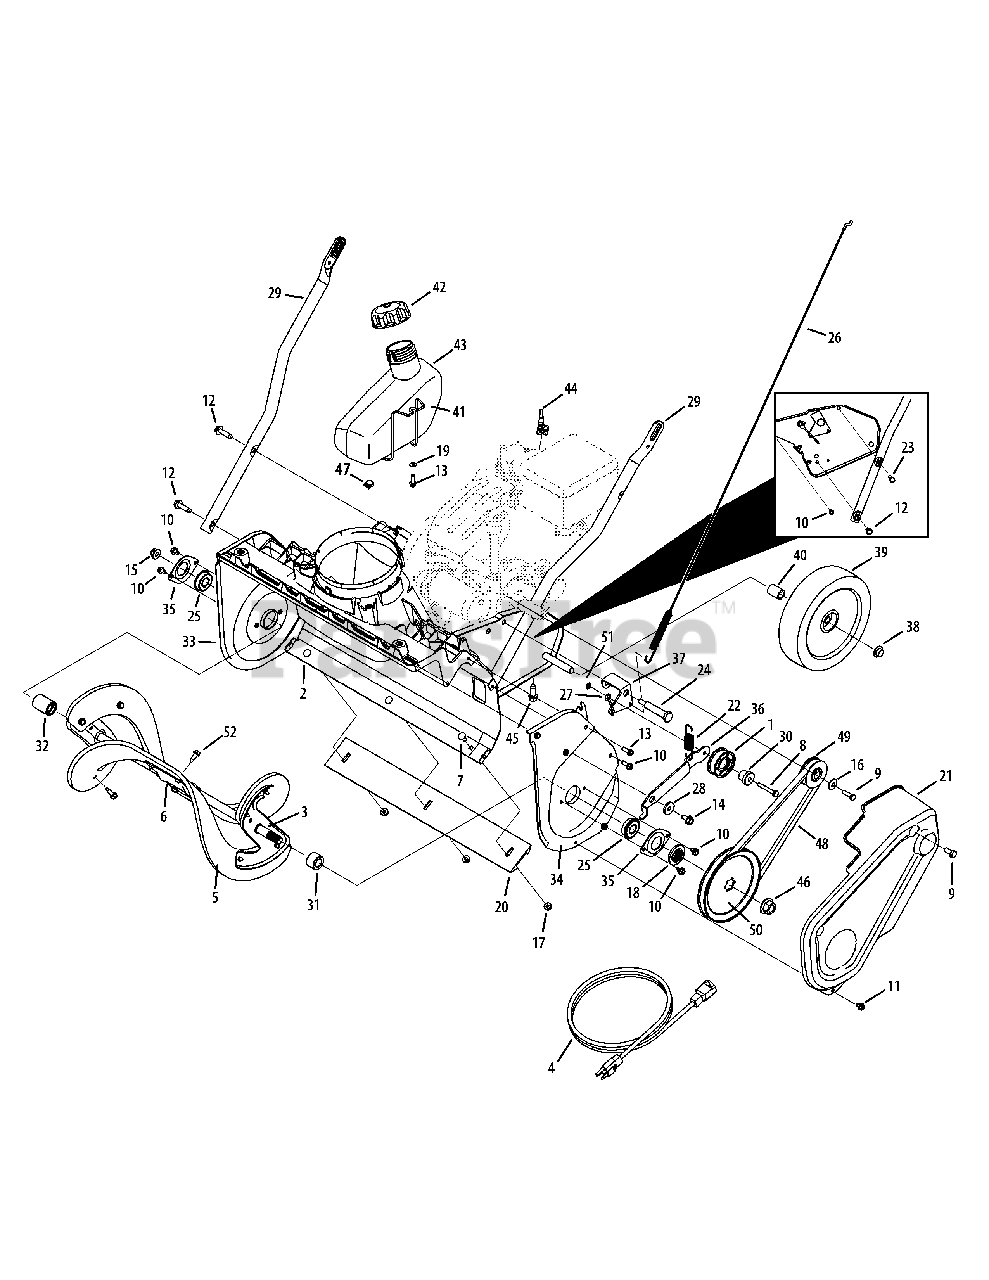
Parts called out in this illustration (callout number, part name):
1	Idler Pulley Assembly
2	Frame - Red
2	Frame - Black
2	Frame - Green
3	Auger Assembly Complete
3	Auger Assembly Axle
4	3-Prong Extension Cord
5	Auger Replacement Kit
6	Center Auger Bracket
6	Hex Washer Screw 1/4-20 x.750
7	Carriage Screw, 1/4-20 x .62
8	Hex Screw, 1/4-20 x 1.50
9	Hex Lock Screw, 5/16-24 x .750
10	Hex Washer Screw, 1/4-20 x .625
11	Hex Washer Screw, 1/4-20 x .500
12	Hex Washer Screw, 5/16-18 x 1.250
13	Hex Washer Screw, 1/4-15 x .750
14	Hex Washer Screw, 5/16-18 x .75
15	Flange Lock Nut, 3/8-16
16	Thrust Washer, .343 x .880 x .062
17	Flange Lock Nut, 1/4-20
18	Pulley Hub
19	Washer, .265 x 1.00 x .030
20	Shave Plate
21	Belt Cover
22	Extension Spring, .70 x 3.035
23	Hex Screw, 5/16-24 x 1.25
24	Shoulder Bolt, 5/16-24 x .496 x 2.18
25	Ball Bearing, .500 x 40mm x 12mm
26	Clutch Cable
27	Drive Cable Wire Support
28	Shoulder Spacer
29	Lower Handle
30	Shoulder Spacer, .260 x .785 x .538
31	LH Auger Spacer
32	RH Auger Spacer
33	RH Auger Plate - Red
33	RH Auger Plate - Black
33	RH Auger Plate - Green
34	LH Auger Plate - Red
34	LH Auger Plate - Black
34	LH Auger Plate - Green
35	Bearing Cup - Red
35	Bearing Cup - Black
35	Bearing Cup - Green
36	Idler Bracket
37	Cable Idler Bracket
38	Push Cap, 1/2
39	Wheel, 8"
39	Wheel, 7"
40	Spacer, .525 x .775 x .835
41	Gas Tank Wire Support
42	Fuel Cap
43	Fuel Tank
44	Choke Extension Lever
45	Hex Washer Screw, 3/8-16 x 1.000
46	Flange Nut, 7/16-20
47	Hose Clamp
48	Belt, .500 x 35.06
49	Pulley Half, .625 x 2.25
50	Pulley, 1/2 x 6.00
51	Push Nut
52	Hex Washer Screw, 1/4-14 x .750
